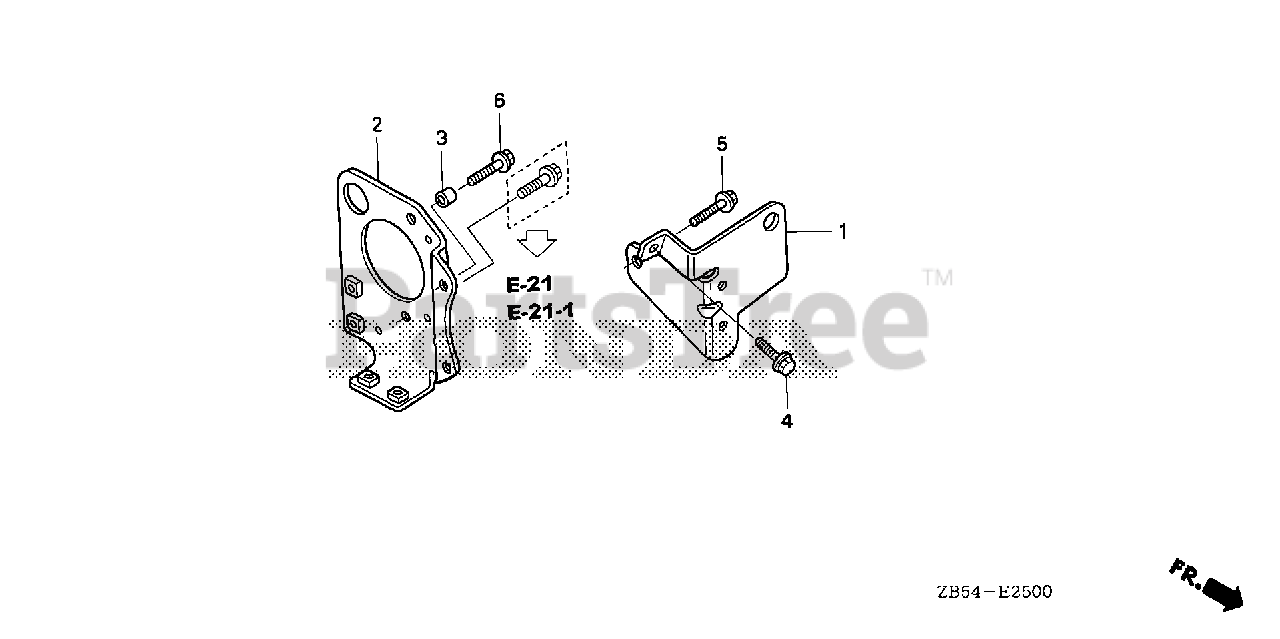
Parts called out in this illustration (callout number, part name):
1	STAY, R. ENGINE MOUNTING
2	STAY, L. ENGINE MOUNTING
3	PIN, DOWEL (10X12)
4	BOLT, FLANGE (8X20) Use up to Engine SN 1609606.
4	BOLT, FLANGE (8X20)
5	BOLT, FLANGE (8X25)
6	BOLT, FLANGE (8X28)
